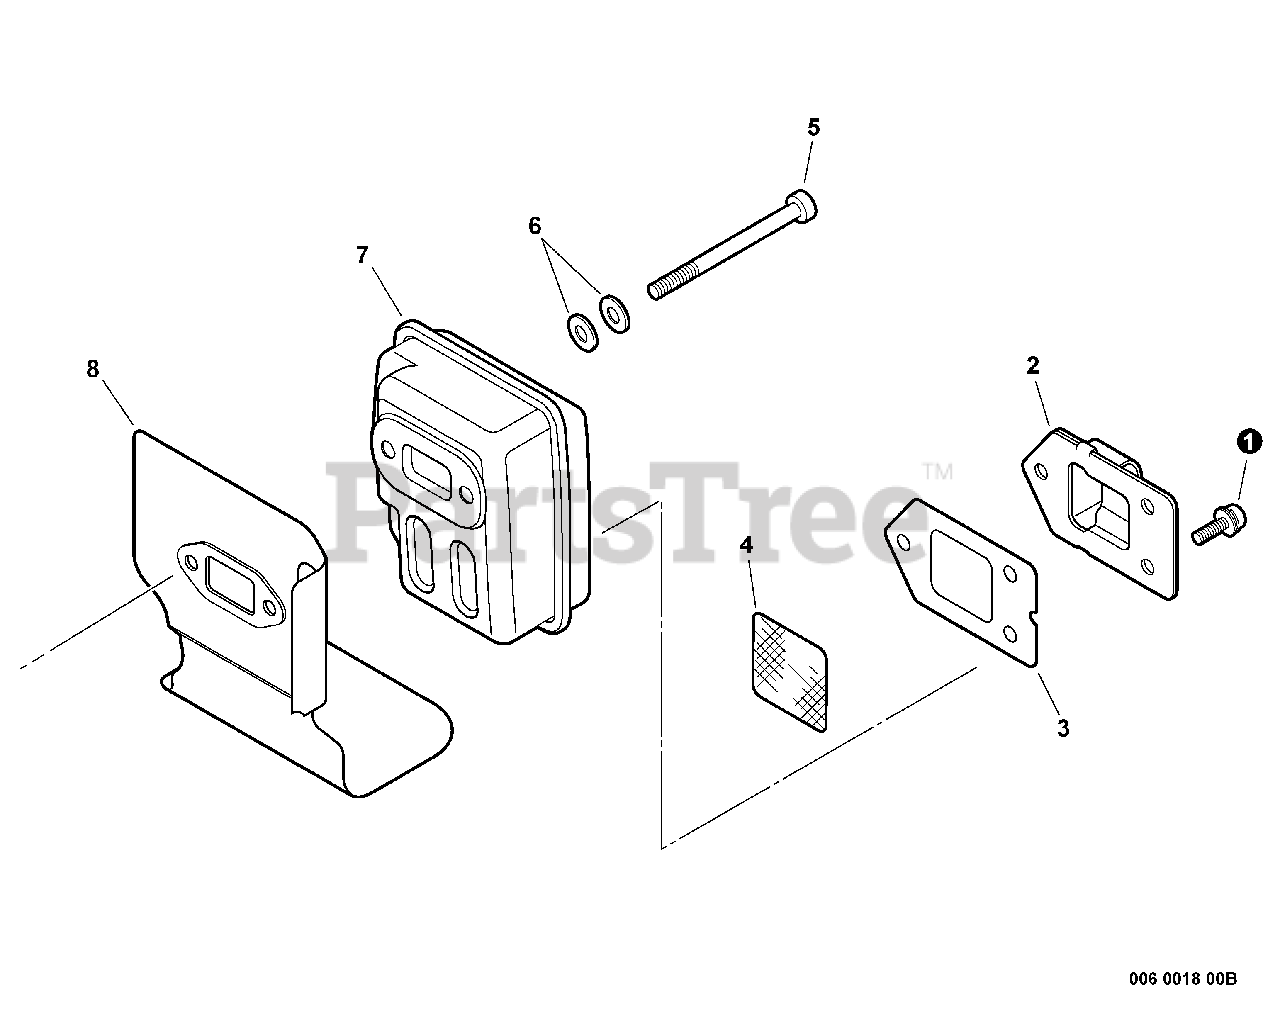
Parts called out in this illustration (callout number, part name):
1	SCREW - 4X10
2	GUIDE, EXHAUST
3	GASKET, EXHAUST
4	SCREEN, SPARK ARRESTOR
5	SCREW - 5X55
6	WASHER - 5
8	SHIELD, EXHAUST
